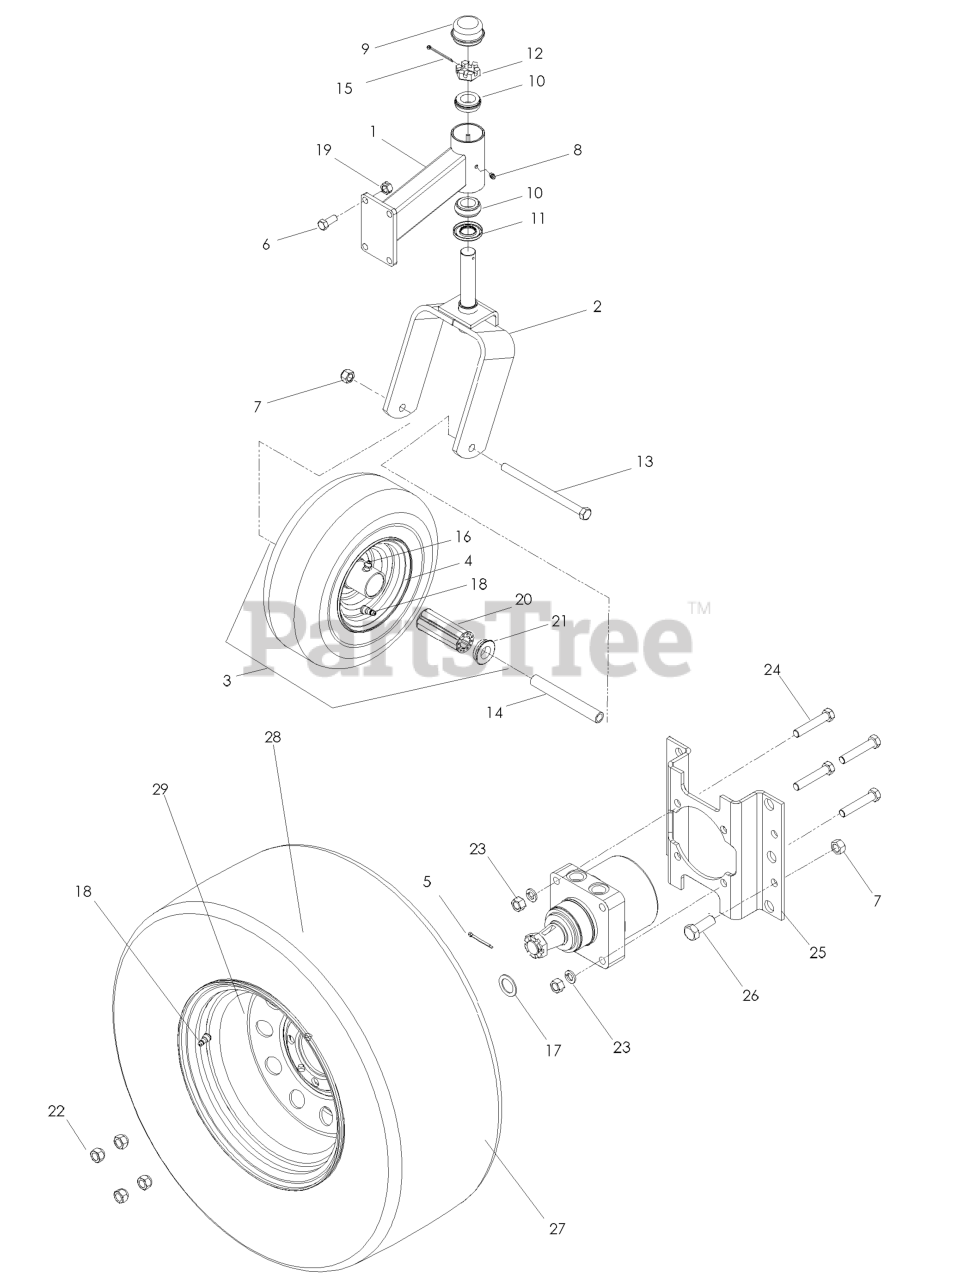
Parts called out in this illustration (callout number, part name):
1	CASTER ARM, ORG
1	FRONT CASTER ARM, ORG
2	CASTER YOKE ORANGE
3	TIRE.ASSEM.13X5-6.SMOOTH.SILVE
4	RIM
5	COTTER PIN
6	HCS 7/16-14 X 1 GR 5 ZD
7	NUT 1/2-13 HEX NYLOC ZD
8	ZERK
9	GREASE CAP
10	TAPERED ROLLER BRG
12	NUT 1"C HEX SLOTTED
13	SCREW 1/2C X 7 1/2 HEX CAP
14	SPACER, CASTER
15	COTTER PIN 1/8 X 2
16	ZERK 1/8 NPT
17	MACHINE BUSHING
18	VALVE STEM TR-412
19	NUT 7/16C CENTERLOCK
20	ROLLER BEARING
21	BEARING RETAINER
22	LUG NUT 1/2F
23	WASHER 1/2" SPLIT LOCK
24	HCS 1/2C X 2 3/4
25	MOTOR STANDOFF, TE, BLK
26	HCS 1/2C X 1 1/4 SERRATED HEAD
27	WHEEL/TIRE.ASM.23X10.5-12.GREY
27	WHEEL/TIRE.ASM.23X9.5-12.GREY
27	TIRE WHEEL ASM 23X8.5-12
27	RP WHEEL.ASM.23X10.5-12.TURFMA
28	TIRE.TURF.MASTER.23X10.5-12
28	TIRE.TURF.MASTER.23X9.5-12
29	RIM 0 OFFSET 8.5" WIDE
29	RIM 1.0" NEG OFFSET 8.5" WIDE
29	12"RIM 2.5" NEG OFFSET 8.5" W
